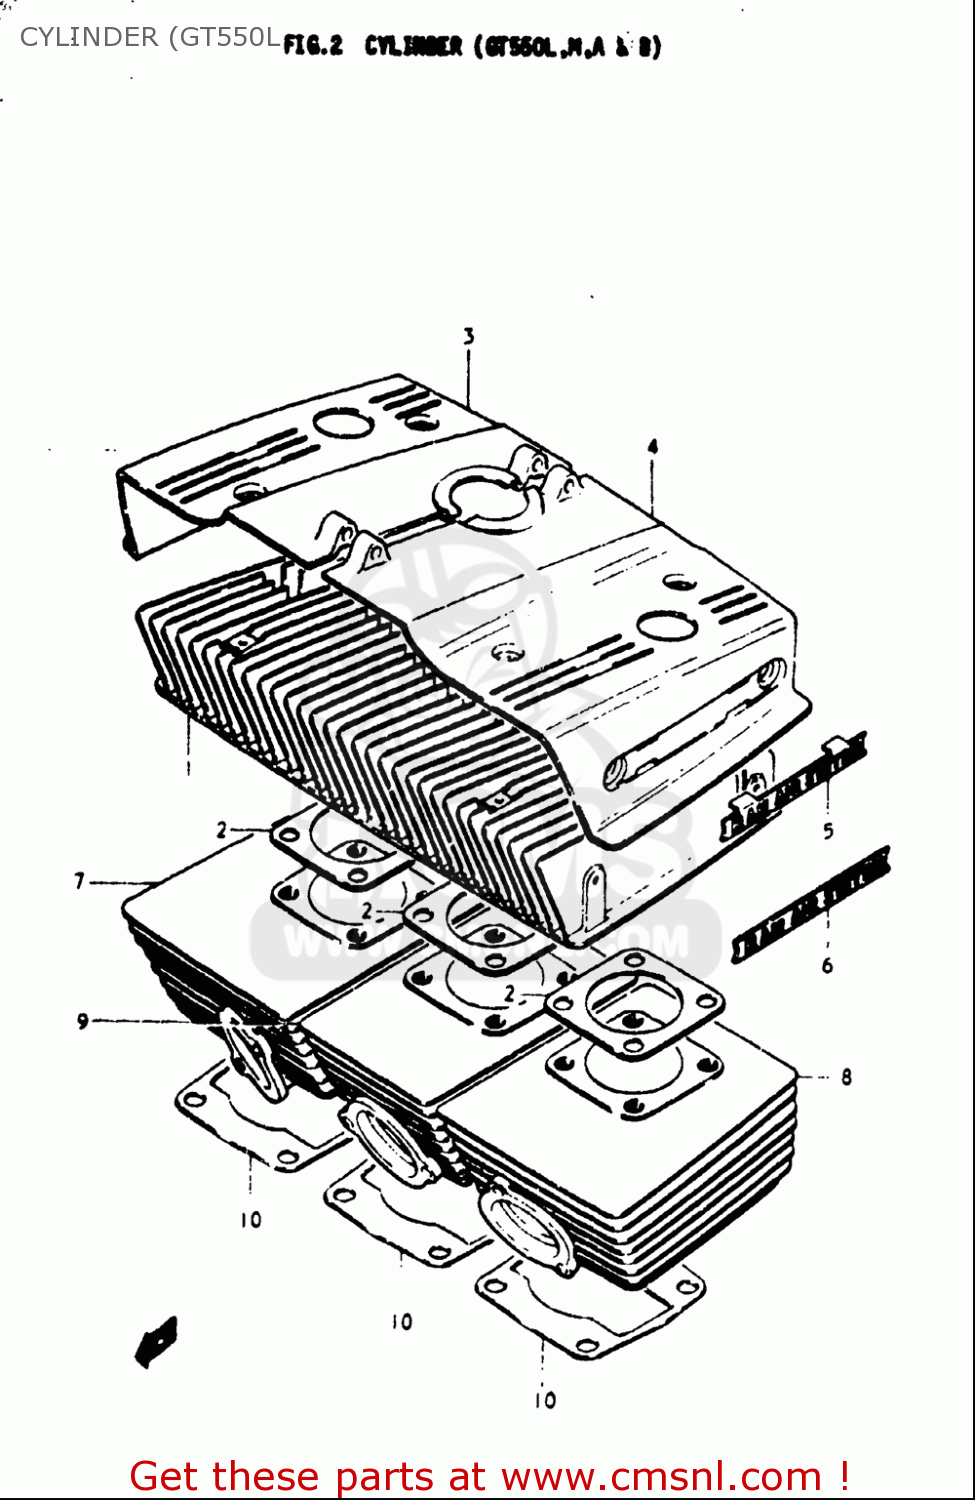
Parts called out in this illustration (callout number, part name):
2	GASKET,CYLINDER HEAD (NAS)
5	EMBLEM,CYLINDER HEAD COVER
6	EMBLEM,CYLINDER HEAD COVER
10	GASKET,CYLINDER (NAS)
